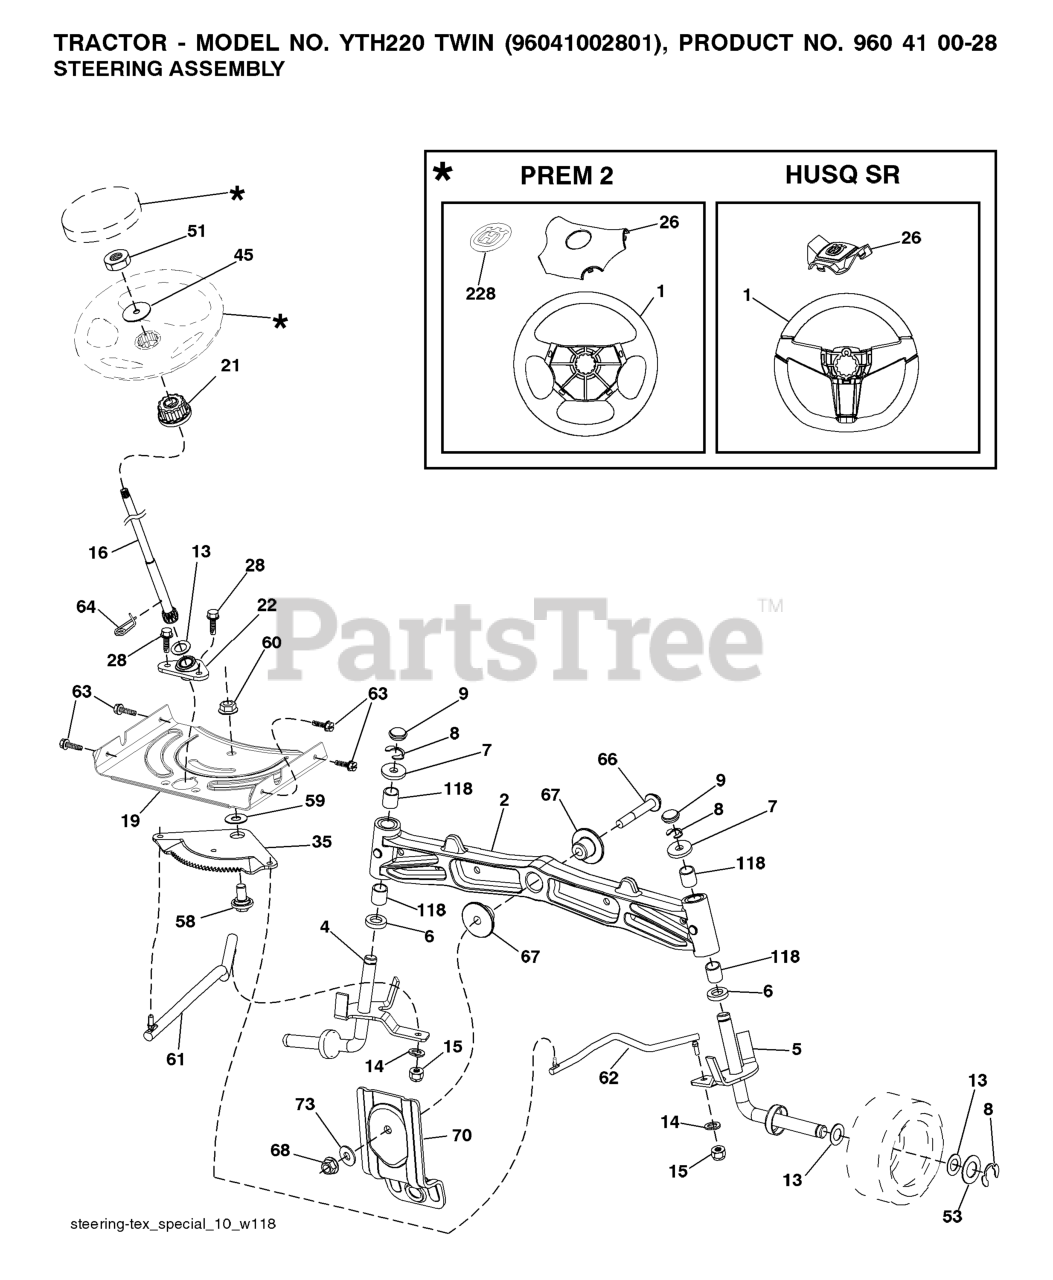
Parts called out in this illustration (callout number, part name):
1	RP WHEEL.STEER.HUSQ.PREM.OVMLD
2	AXLE.CAST.IRON
4	SPINDLE.ASM.LH.16"TIRE.CE
5	SPINDLE.ASM.RH.16"TIRE.CE
6	THRUST WASHER
9	CAP.SPINDLE.BLACK
14	WASHER, LOCK 3/8
15	NUT CROWNLOCK 3/8-24
16	SHAFT.STEER.STEALTH.DD
19	PLATE.STEER.DDL.NLT/NG
21	ADAPTER, WHEEL STNG..
22	BUSHING.ASM.STEERING.A
26	RP INSERT.CAP.WHL.STRG.HUSQ.
28	SCREW, 3/8-16X3/4
35	GEAR.SECTOR.PLATE.DDL.
45	WASHER 9/16"ID, 2 3/8"OD
51	NUT.HEX.1/2-20
53	WASHER.HARDENED
58	BOLT.SHOULDER.SECTOR.P
59	WASHER.THURST.SECTOR.S
60	NUT FLANGE LOCK 5/8-11
61	DRAGLINK.LH.BALLSTUD.D
62	DRAGLINK.RH.BALLSTUD.D
63	SCREW
64	RETAINER.CLIP.SPRING.S
66	BOLT HEX FGHD 7/16-14 X 3 SERR
67	BUSHING.PM.FRONT AXLE
68	NUT.LOCK.FLANGE.7/16
69	WASHER.1.5X.505X.118
70	BRKT.DECK.SUSPENSION.F
118	BUSHING, AXLE CAST
228	DECAL.WHEEL.STRG.LGN.H
